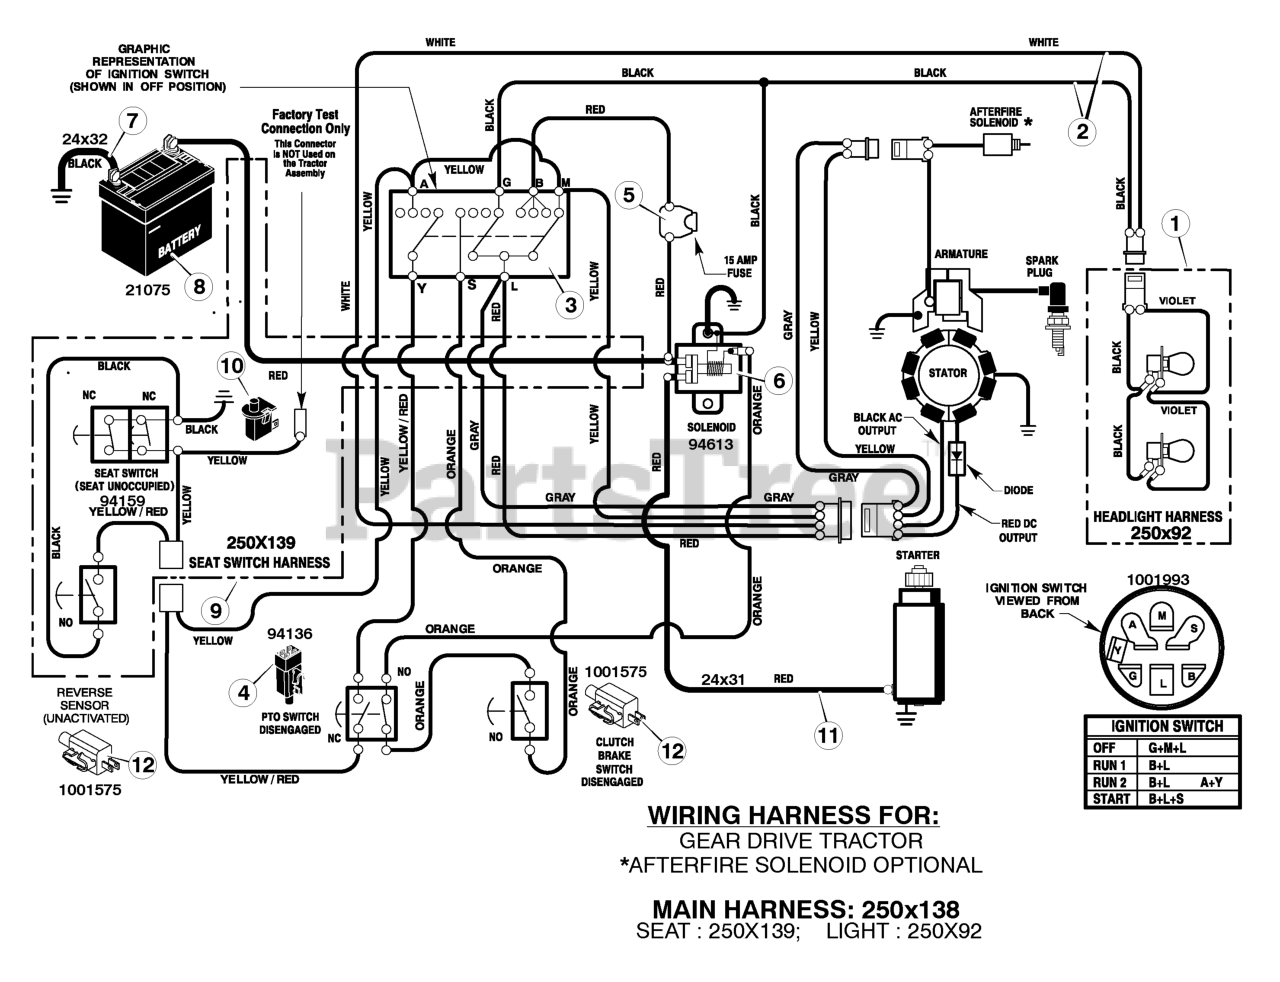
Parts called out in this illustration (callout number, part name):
1	Harness, Light Wire
2	Harness, Chassis Wire
3	Switch, Ignition
4	Switch, Limit (PTO)
6	Solenoid
7	Cable, Battery Ground
8	Battery
9	Harness, Seat Switch Wire
10	Switch, Seat Sensor
12	Switch, Select Reverse / Clutch Brake
